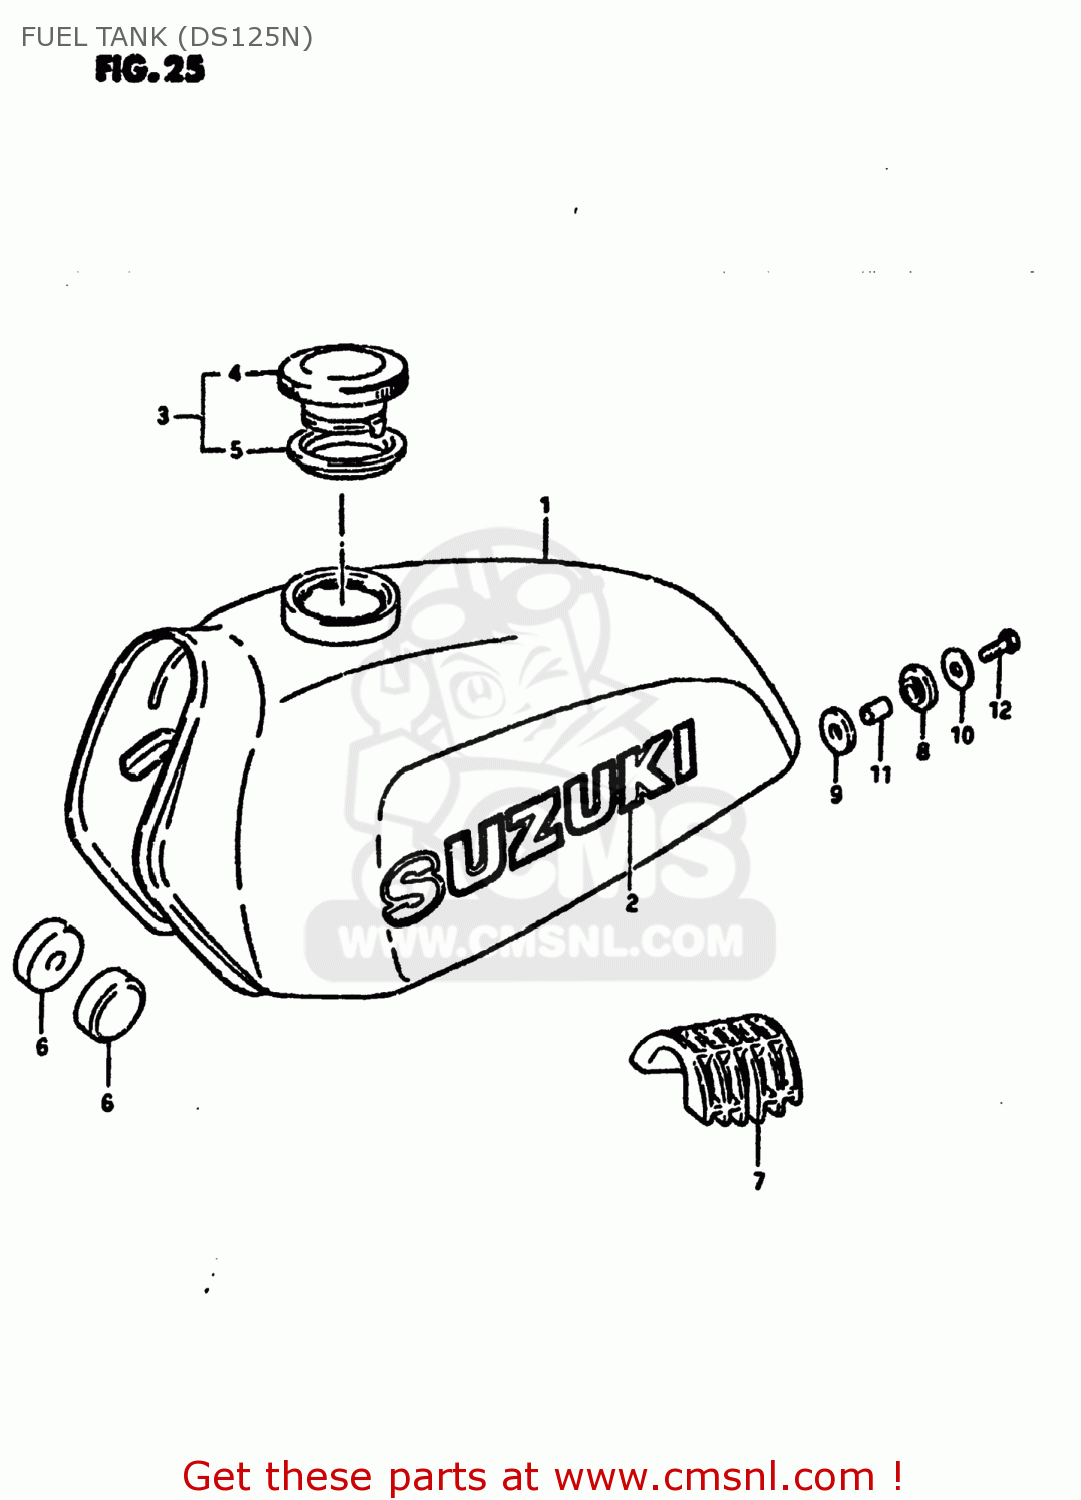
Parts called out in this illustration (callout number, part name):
1	TANK ASSEMBLY,FUEL
2	EMBLEM
3	CAP ASSY,FUEL TANK FILLER
4	CAP,FUEL TANK
5	GASKET (NAS)
6	CUSHION
7	CUSHION
8	CUSHION
9	CUSHION
10	WASHER (8.5X29X1.6)
11	SPACER (8.2X12X17)
12	BOLT (8X30)
